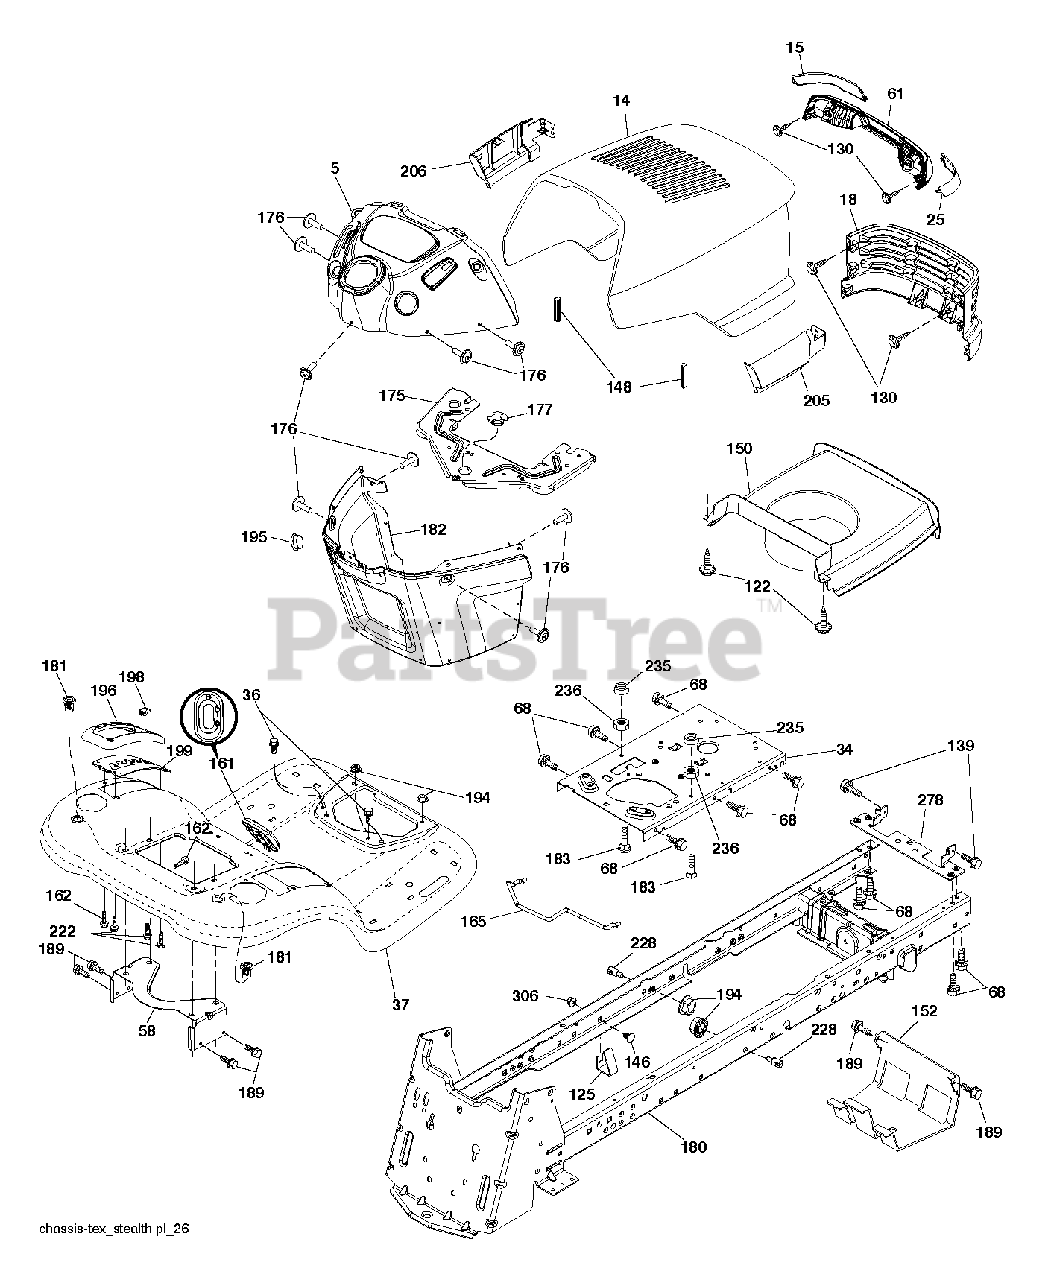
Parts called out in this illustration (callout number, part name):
5	DASH.STEALTH.SRV.RS.428
14	HOOD ASM.STEALTH.HOR-LOUV.667
15	LENS LH
18	GRILLE.STEALTH.GT.BLACK
25	LENS RH
36	SCREW 5/16"
58	BRKT.SUPPORT.FNDR/TANK
122	SCREW.WSHD.HEX10-32X5/8
125	Fuel Line Clip
130	SCREW.#10 X 0.750.BOS THREAD
139	BOLT, SHOULDER 5/16-18
146	BOLT.RDHD.SHT.SQNK.3
148	EXTRUSION BUMPER
152	SHIELD BROWNING
161	CONSOLE.FUEL.WINDOW.STGT.BLACK
162	SCREW.HI-LO.CONSOLE
165	SUPPORT.TANK.REAR.W/TE
175	CROSSMEMBER.
176	SCREW.#10-24X5/8.RN.QU
177	BUSHING,STEERING
180	CHASSIS.GT.SLOPED.DRAWBAR.
181	FEND/FTRST.PCH.CPH.NFW
182	DASH.LOWER.
183	BOLT.5/16-18X1-1/4 FULL THD
189	SCREW
194	NUT LOCK HEX FLANGE 5/16-18
195	PLUG.HOLE.DASH.LOWER.12V.BLK
198	INDICATOR.DECK.LIFT.RED
199	PLATE DECK LIFT
205	SKIRT.GRILLE.STEALTH.RH
206	SKIRT.GRILLE.STEALTH.LH
222	SCREW.1/4-20X5/8
228	STUD.FASTNER.W/ANTI-ROTATE
235	SPACER FENDER
236	NUT.CENTERLOCK.5/16-
278	BRKT.HOOD/MUFF.STEALTH
306	NUT LOCK FLG 3/8-16 UNC
